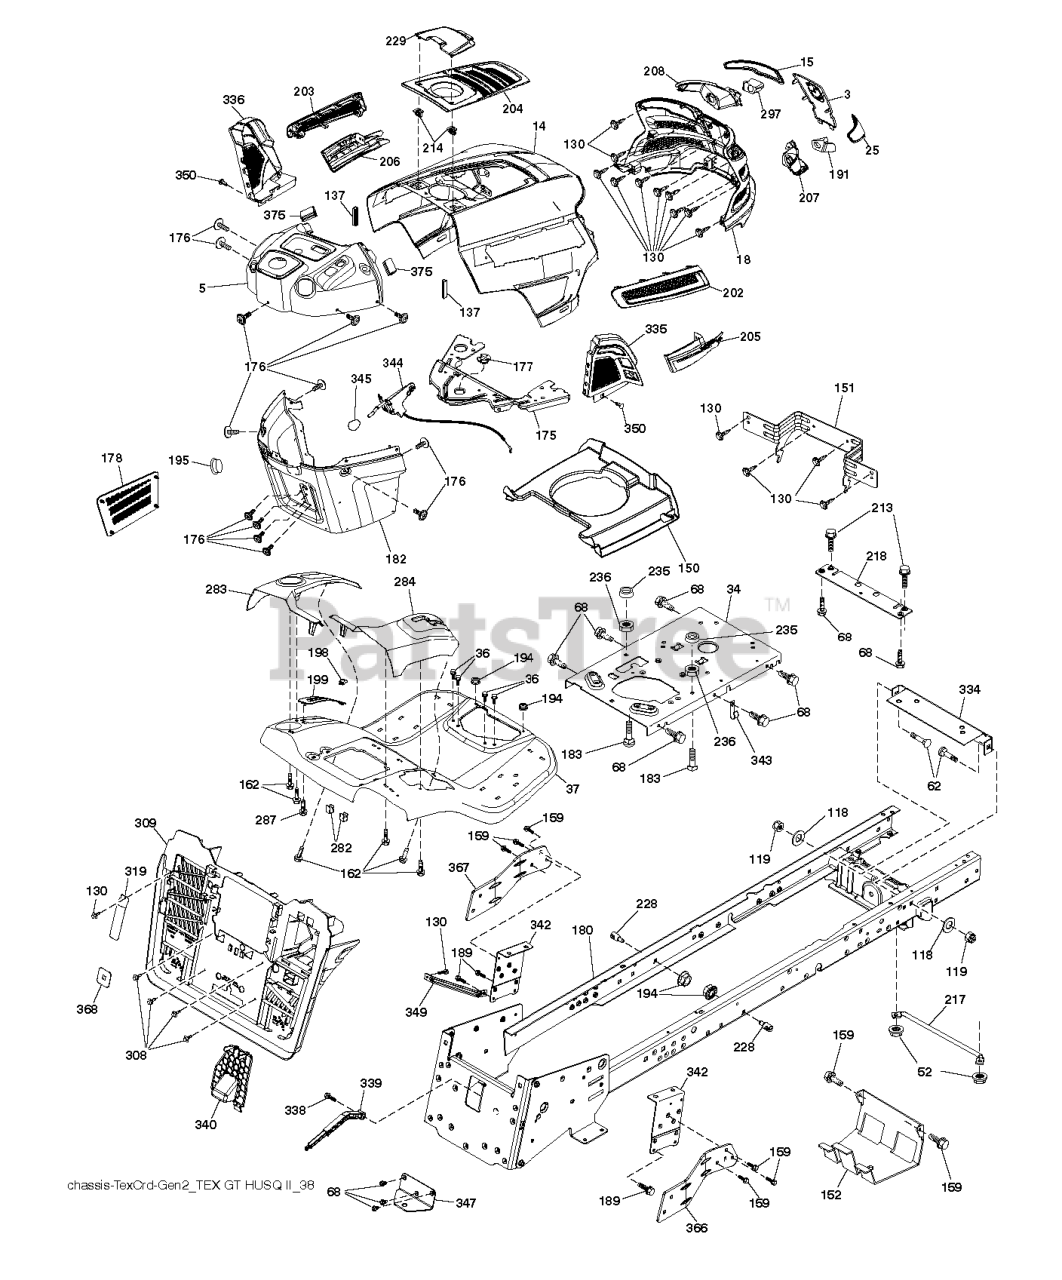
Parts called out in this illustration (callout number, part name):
3	APPLIQUE.SUBASM.GT.HUSQ.II
5	GT2.DASH.UPPER.W/BUMPERS
14	HOOD.ASM.HUSQVARNA.GT.TEX.ORAN
15	LENS.HEADLIGHT.LH.GTII.2011
18	GRILLE.SUBSTRATE.2011.
25	LENS.HEADLIGHT.RH.GTII.2011
34	PLATE.ENGINE.10GA.CRD.GENII
36	SCREW 5/16"
37	FENDER.TEX.SRD.CRD.FRN.GUARDS
52	LOCKNUT
62	BOLT D
68	SCREW LT
118	WASHER
130	SCREW.#10 X 0.750.BOS
137	BUMPER DASH
150	AIR.DUCT.GTV.BLACK
151	BRACKET.PIVOT.HOOD.GT.HUSQ.II
152	SHIELD.BROWNING.PNT.GT.V2
159	SCREW, 3/8-16X3/4
162	SCREW.HI-LO.CONSOLE
175	PLATE.CROSSMEMBER.HUSQ
176	SCREW.#10-24X5/8.RN.QU
177	BUSHING, STEERING
178	CARGO.ASM.NET.TXGT.W/C
180	WELDMENT.CHASSIS.TEX.CRD.GEN.2
182	DASH DASH LOWER
183	BOLT.5/16-18X1-1/4 FULL THD
189	SCREW
191	INSERT.REFLECTIVE.RH.HUSQ.GTII
194	NUT LOCK HEX FLANGE 5/16-18
195	PLUG.HOLE.DASH.LOWER.12V.BLK
198	INDICATOR.DECK.LIFT.RED
199	PLATE DECK LIFT
202	VENT.SIDE.RH.GT.HUSQ.II.
203	VENT.SIDE.LH.GT.HUSQ.II.498
204	VENT.TOP.EXTERNAL.FILL.GT2.GRE
205	SIDE.TRIM.RH.GT.HUSQ.II
206	SIDE.TRIM.LH.GT.HUSQ.II.GRAY
207	BEZEL LIGHT.RH.GT.II.MYLAR
208	BEZEL LIGHT.LH.GT.II.MYLAR
213	BOLT
214	CLIP.RETAINER.TINNER.
217	ROD.PIVOT.HOOD
218	X-PIECE.HOOD.STOP.NON/
228	STUD.FASTNER.W/ANTI-ROTATE
229	LID.EXT.FILL.GT.HUSQ2.BLACK
234	BUMPER.HOOD.TEX.HUSQVARNA
235	SPACER FENDER
236	NUT.CENTERLOCK.5/16-
282	CLIP.RETAINER.CONSOLE.LT.HUSQ
283	CONSOLE.DECKLIFT.CRDII.498
284	CONSOLE.PEDAL.HYDRO
287	SCREW 1/4X20
297	INSERT.REFLECTIVE.LH.HUSQ.GTII
308	BOLT.5/16-18UNCX3/4 W/SEMS.BLK
309	BACKPLATE.ASM.CRDII.ANTIROTAT
319	LEVER.BAG.CRDII.ANTIROTATION
334	BRACKET.ENGINE
335	COVER-LH.LOWER.DASH.GT2.BLACK
336	COVER.LOWER.DASH.RH.BLACK
338	BOLT BOLT SHOULDER
339	LEVER LEVER BAGGER
340	BATTERY.DOOR.TEX.CRD.GEN.2,1
342	SUPPORT SUPPORT FENDER
343	CLIP CLIP
344	CONTROL.EZ.MULCH.TEX/CRD
345	RP KNOB.OVAL.TAPERED.3/8-16BLK
347	HITCH HITCH TOW TEX CRD GEN 2
349	BRACKET.SUPPORT.LRVB/CRD
350	CLIP.X-MAS.TREE
366	BRACKET.RH.FRONT.BAGGER.BLACK
367	BRACKET.LH.FRONT.BAGGER.BLACK
368	FULL.LEVER.BAGGER.TEX.CRD
